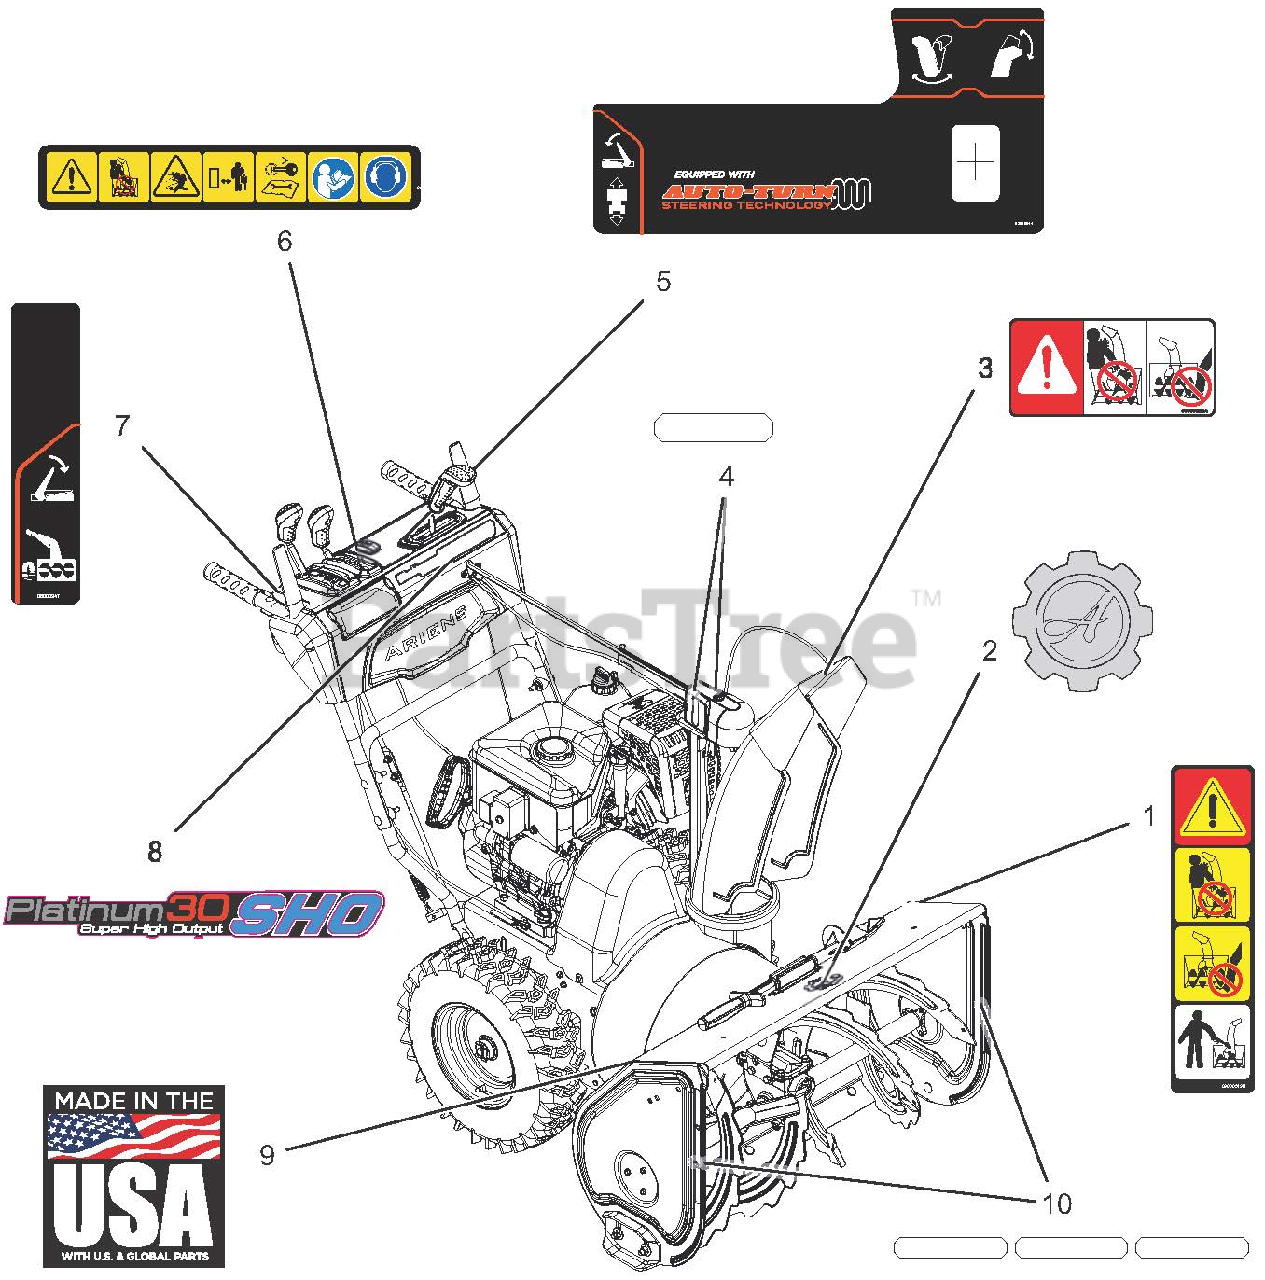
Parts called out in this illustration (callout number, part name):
1	DECAL, DANGER - ROTATING PARTS
2	DECAL, ARIENS-GEAR BADGE
3	DECAL, DANGER
4	DECAL,REFLECTIVE,GEAR COVER
5	DECAL,CONTROL-LG QT2
6	DECAL,DASH - SAFETY
7	DECAL,CONTROL-RH CONTROL
8	DECAL, DASH, PLATINUM 30 SHO
9	DECAL, MADE IN USA
10	DECAL,REFLECTIVE,HOUSING
